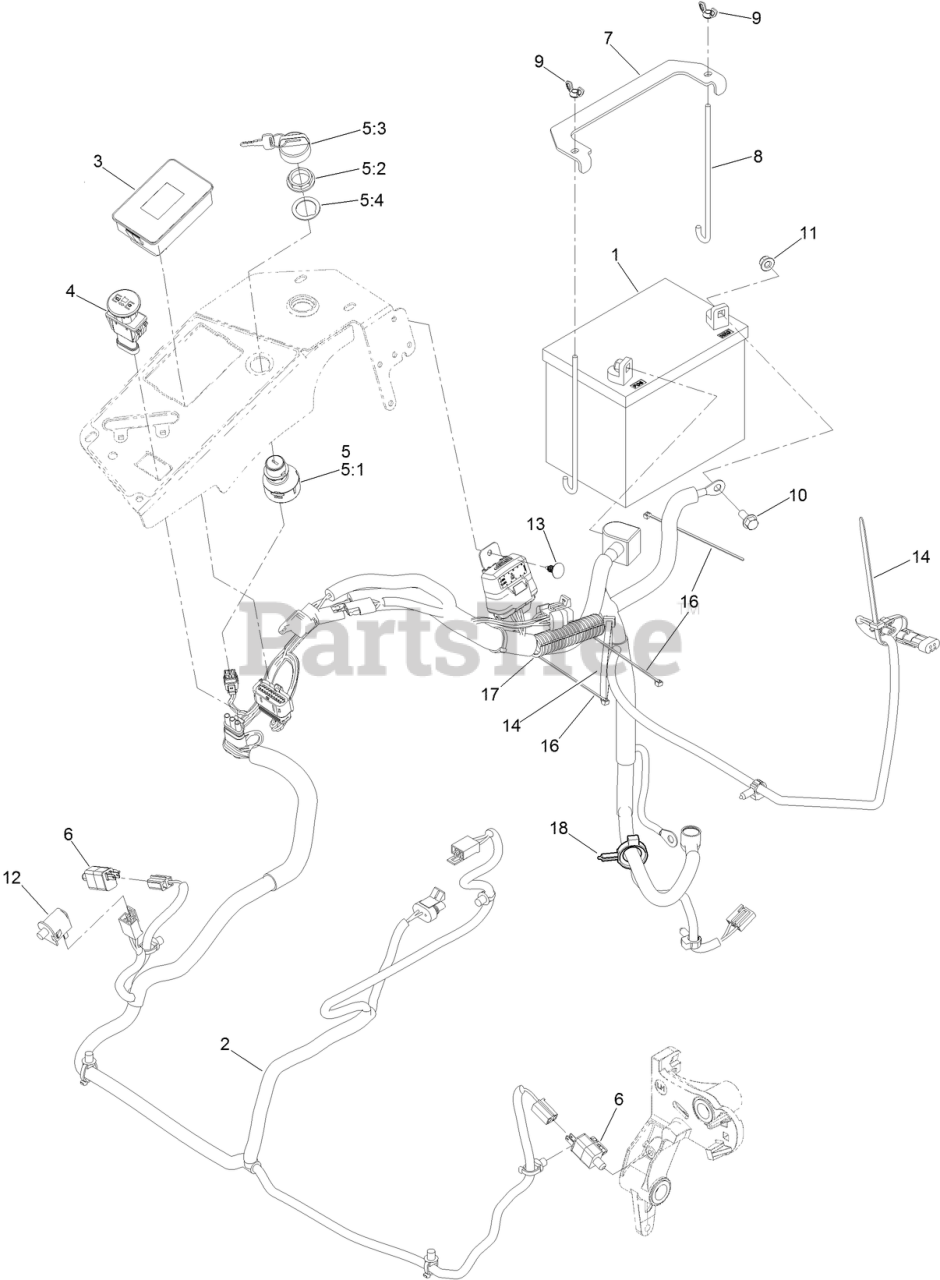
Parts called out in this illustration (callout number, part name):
1	BATTERY-DRY
2	WIRE HARNESS ASM
3	METER-HOUR
4	SWITCH-PTO, SEALED
5	IGNITION SWITCH ASM
5:1	SWITCH-IGNITION
5:2	NUT-MOUNTING
5:3	IGNITION KEY SET
5:4	WASHER-BACKUP
6	SWITCH
7	STRAP-TIE DOWN, BATTERY
8	BOLT-HOLDDOWN
9	WINGNUT
10	SCREW-HHF
11	NUT-HF, NI
12	SWITCH-BAIL
13	PLUG-PLASTIC
14	TIE-PLASTIC
16	TIE-CABLE
17	COVER-HOSE
18	CLAMP-HOSE
